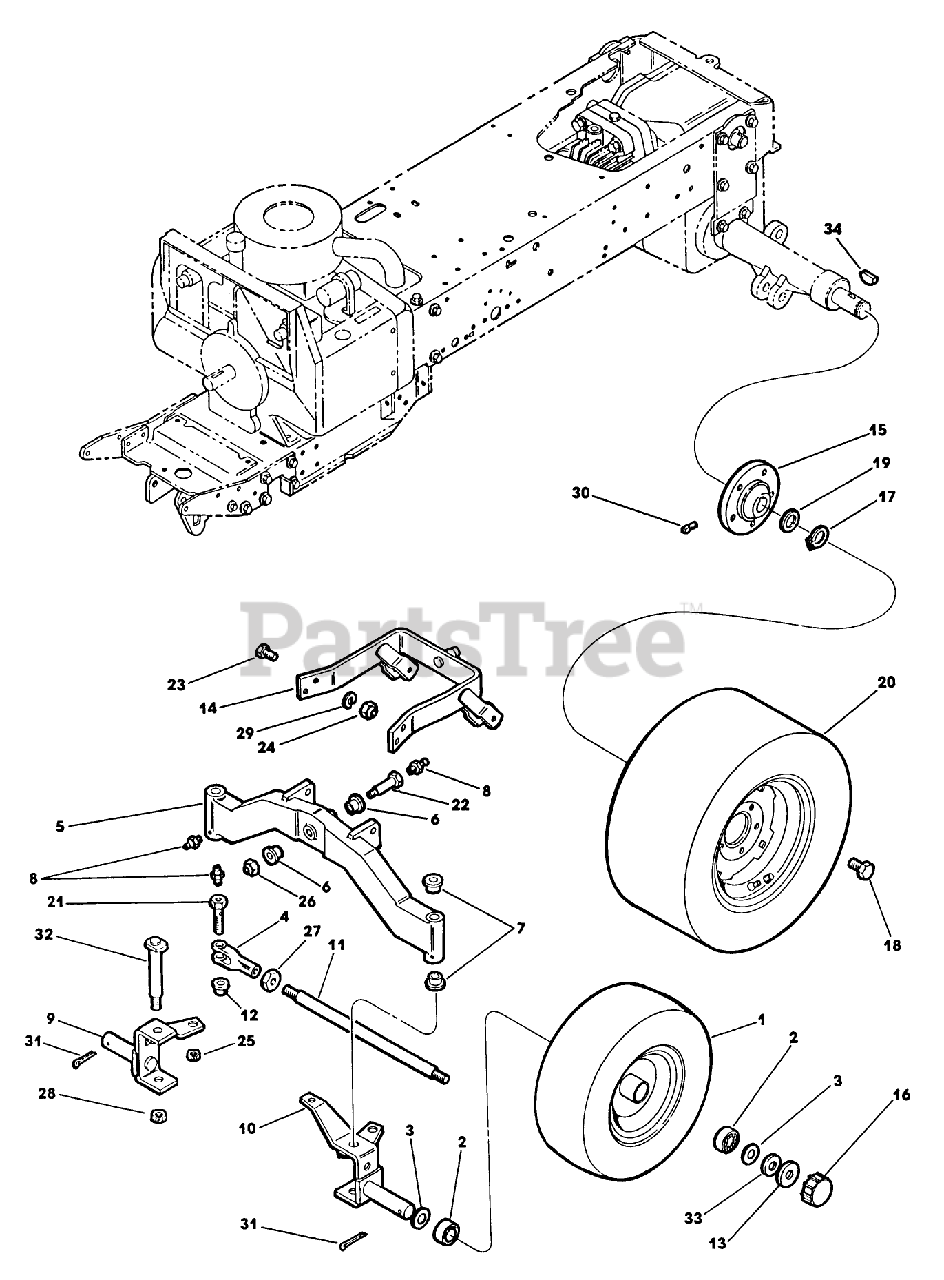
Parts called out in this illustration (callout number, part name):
4	CLEVIS
12	SPACER
13	WASHER
14	SUPPORT AY-AXLE PV *B
15	HUB - WHEEL S
24	NUT-LOCKING
25	NUT-HEX CONE LOK
26	NUT-HEX
29	WASHER
32	PIN AY-KING
34	KEY - WOODRUFF
